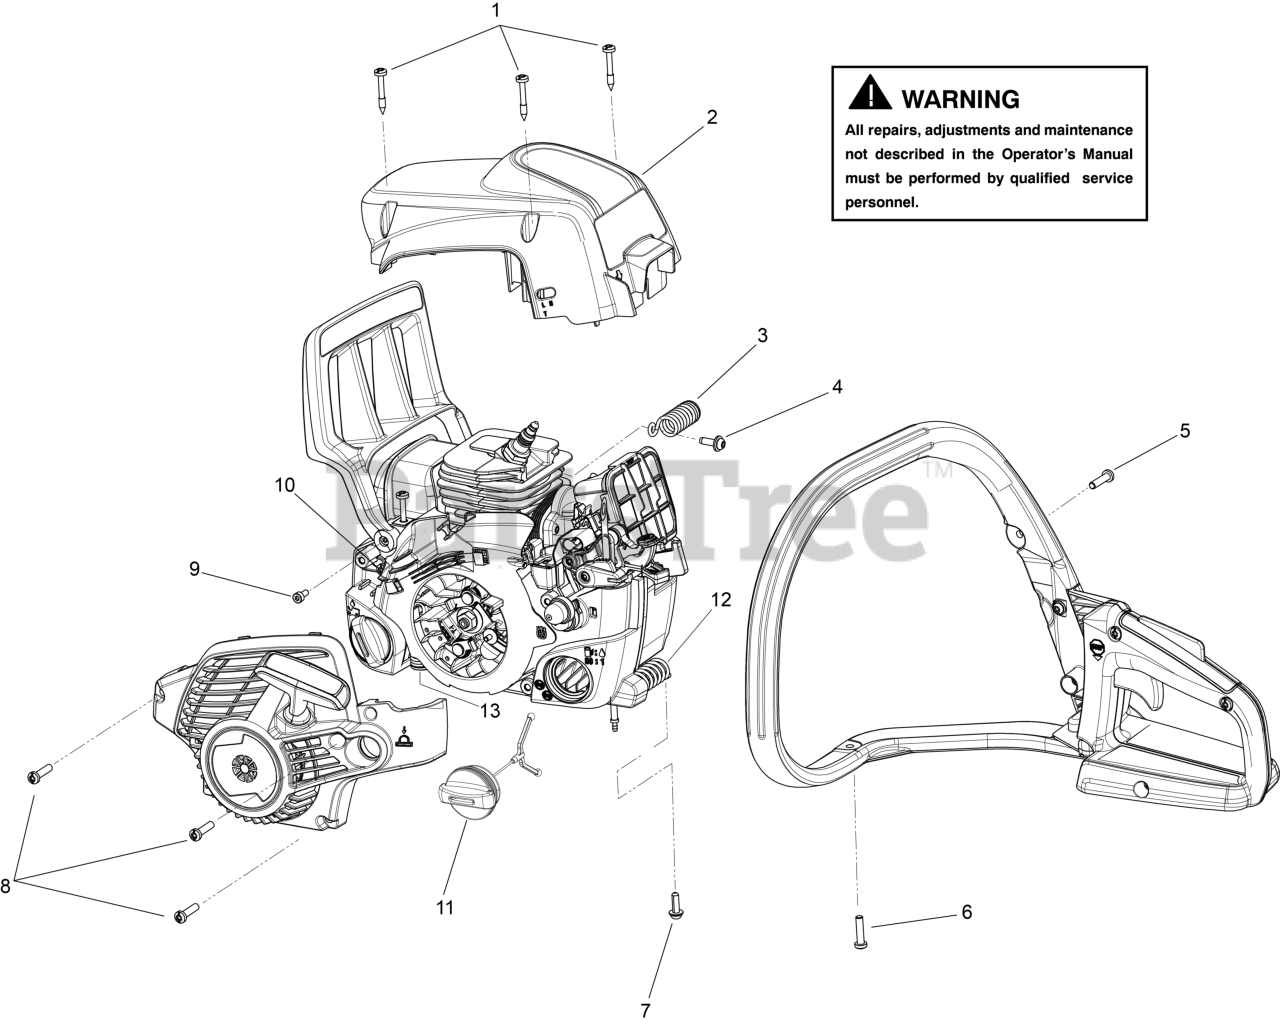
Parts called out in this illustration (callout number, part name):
1	Screw p
2	SHIELD CYLINDER
4	M5.0X0.8X16 TT TRX SEMS
5	SCREW M5.38-14X22.225MM
6	SCREW M5.38-14X22.225MM
7	SCREW,FRONT HBAR 36/41
8	SCREW M5.38-14X22.225MM
9	SPRING HANDGUARD
10	SCREW M5.38-14X22.225MM
11	TANK CAP ASSY
12	SPRING REAR ISOLATOR
